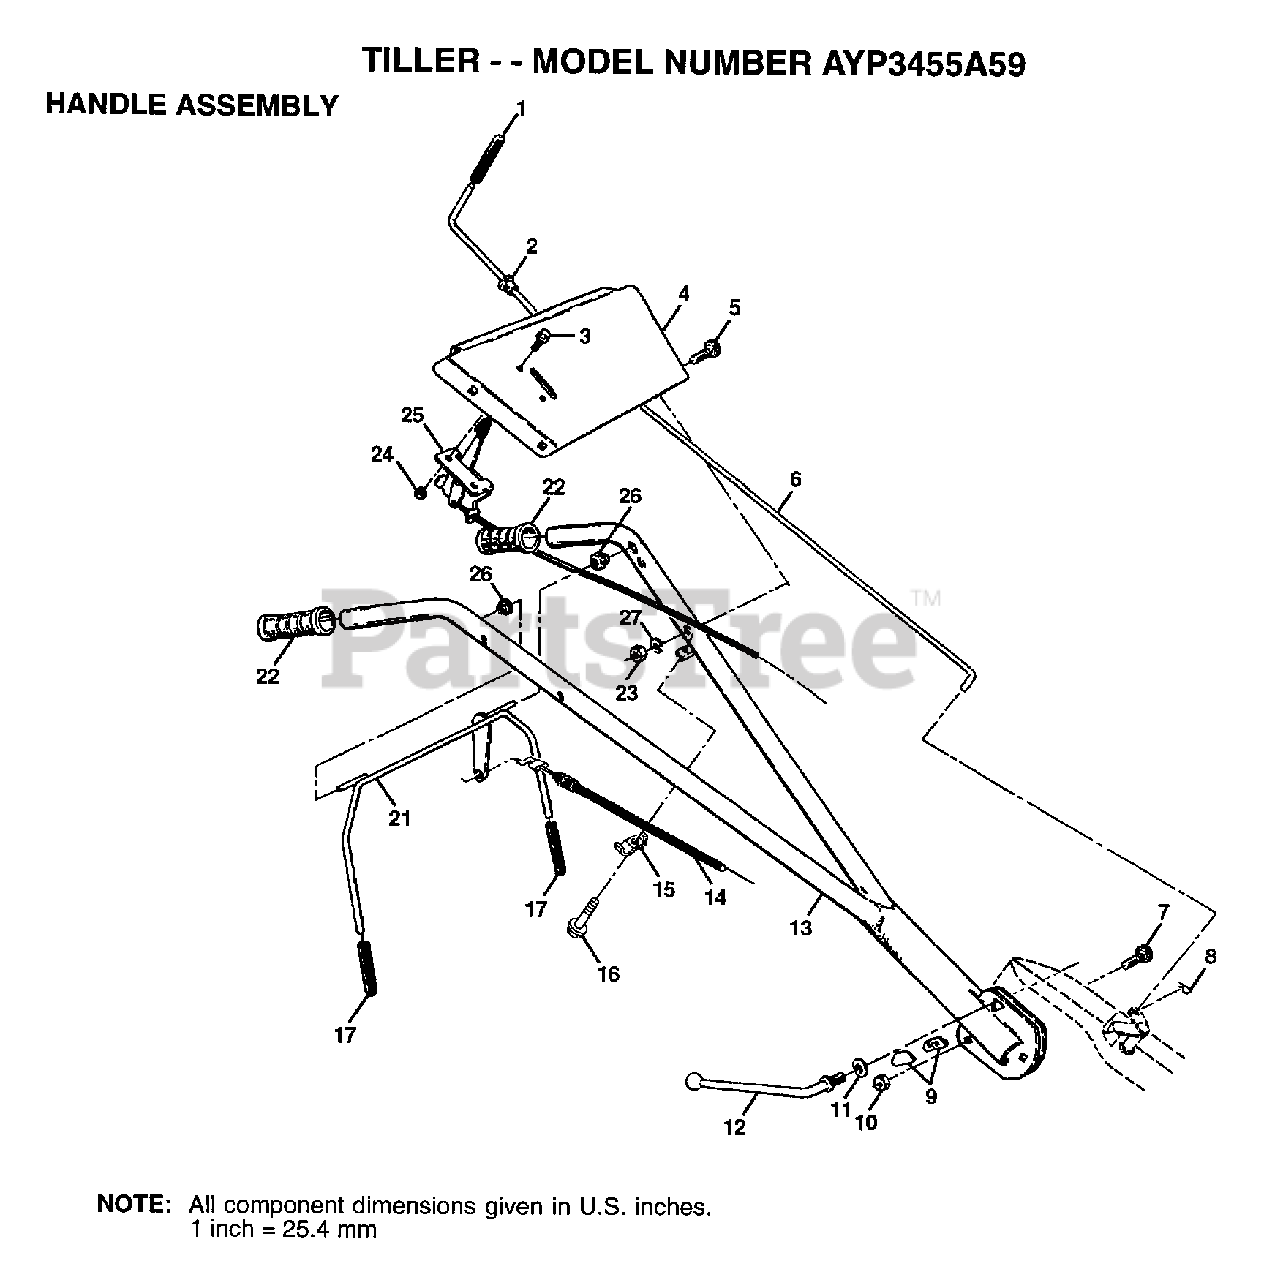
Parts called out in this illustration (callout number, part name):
1	GRIP TI
2	BUSHING
3	SCREW.PNHD.10-24
4	BRACKET.HDLE.SKLS
5	BOLT CARRIAGE CRT
6	ROD SHIFT CRT
7	BOLT D
8	RETAINER M
9	LOCK CRT
10	LOCKNUT
11	WASHER CRT
12	LEVER LOCK CRT
14	CABLE.CLUTCH.48.Z
15	CONDIUT CLIP T
17	GRIP BAR CRT
18	SHOULDER BOLT ST
19	LOCKWASHER
21	HANDLE BAR CRT
22	GRIP HDLE NUBBED
23	NUT
25	"CONT,THROTTLE"
27	LOCKWASHER
